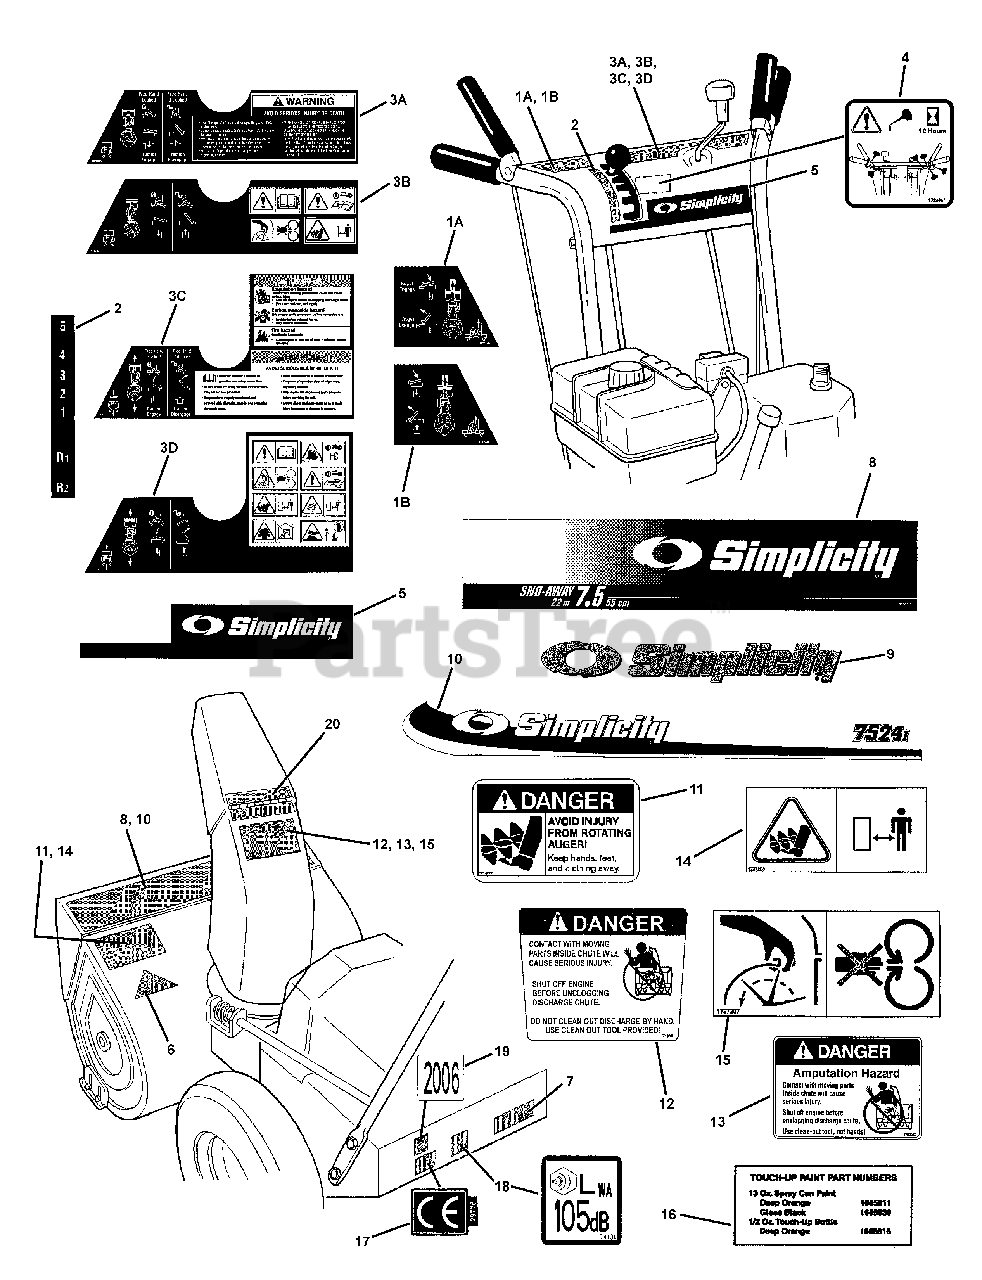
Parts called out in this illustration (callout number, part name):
1A	DECAL, Dashboard- RH
1B	DECAL, Dashboard- RH- Euro
2	DECAL, Shift Pattern
3A	DECAL, Dashboard- LH
3B	DECAL, Dashboard- LH- Euro
3C	DECAL, Dashboard, Top, LH
3D	DECAL, Dashboard, Top, LH (Euro)
4	DECAL, Lube- Controls
5	DECAL, Dash Front - Simplicity
6	DECAL, OPEI (Not Serviced)
7	I.D. Tag (Not Serviced)
8	DECAL, Stripe- Simplicity (7.5hp, 22") shown
9	DECAL, Dash Front - Simplicity
10	DECAL, Stripe- Simplicity (7.5hp, 24")
11	DECAL - Danger, Auger
12	DECAL, Danger, Chute/Deflector
13	DECAL, Danger, Chute/Deflector (Amputation Hazard)
14	DECAL, CE- Auger Warning
15	DECAL, Chute Warning
16	DECAL, Touch-Up Paint
17	DECAL, Euro Community
18	DECAL, Sound 105
19	DECAL, 2005 Year of Manufacture
19	DECAL, 2006 Year of Manufacture (shown)
20	DECAL- Hinge (Orange)
